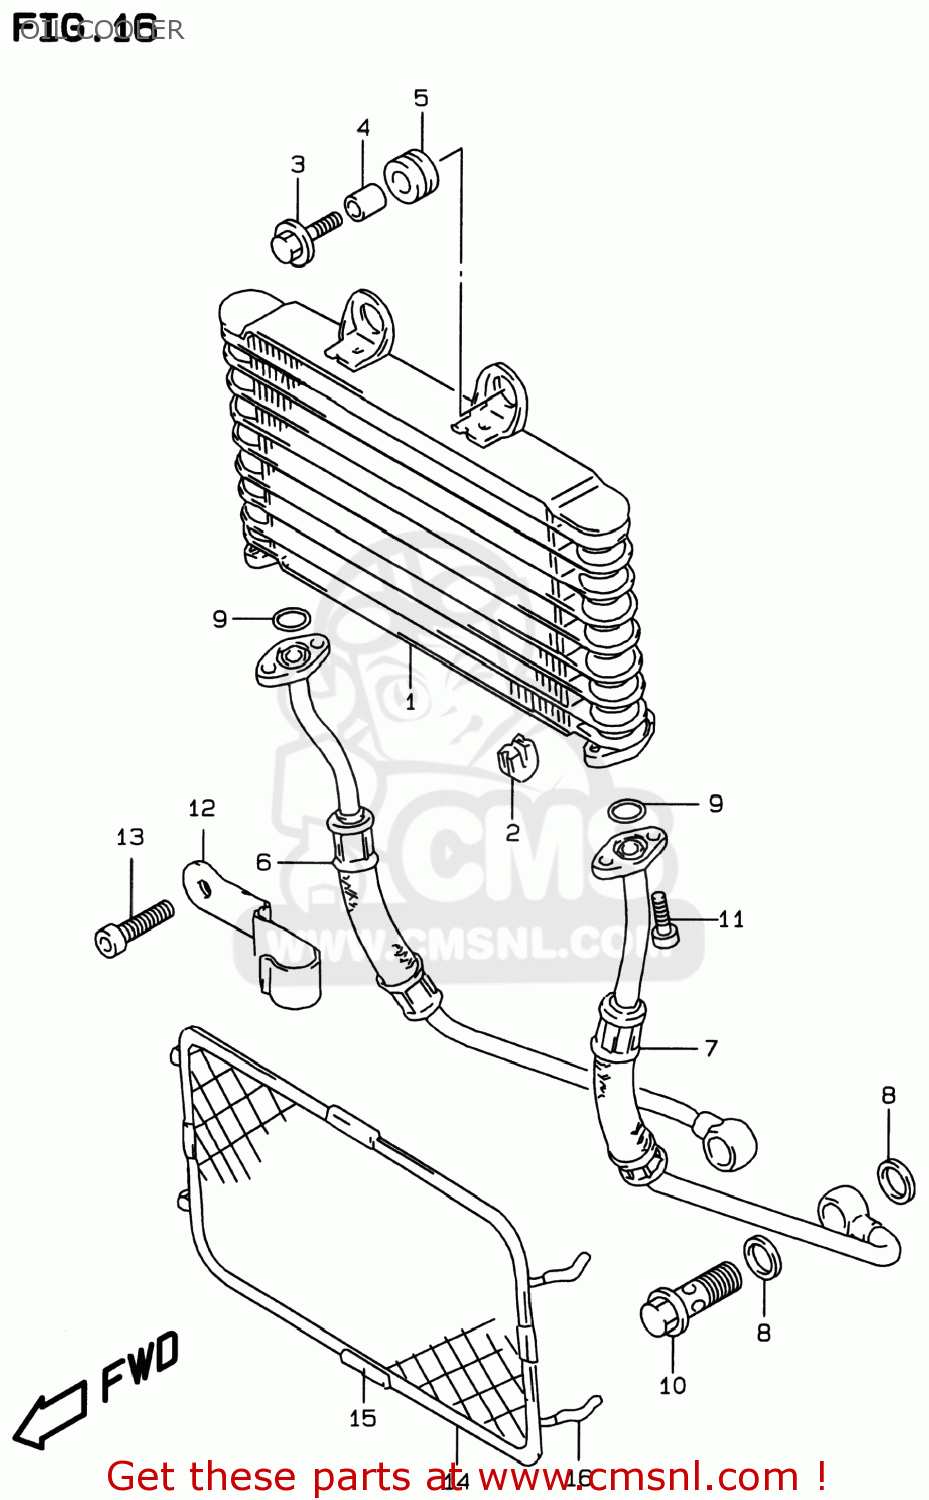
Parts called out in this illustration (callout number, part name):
1	COOLER ASSY,OIL
2	CUSHION,OIL COOLER NO.2
3	BOLT 6X20
4	SPACER(6.5X10X10)
5	CUSHION
6	HOSE,OIL COOLER,RIGHT
7	HOSE,OIL COOLER,LEFT
8	GASKET(16X22X2) (NAS)
9	O RING(D:2.4,ID:12.3)
10	BOLT UNION
11	BOLT,OIL FILLE
12	CLAMP,OIL HOSE
13	BOLT,STRANGER
14	GUARD COMP,OIL COOLER
15	PROTECTOR,CTR
16	HOSE(3X5X600)
